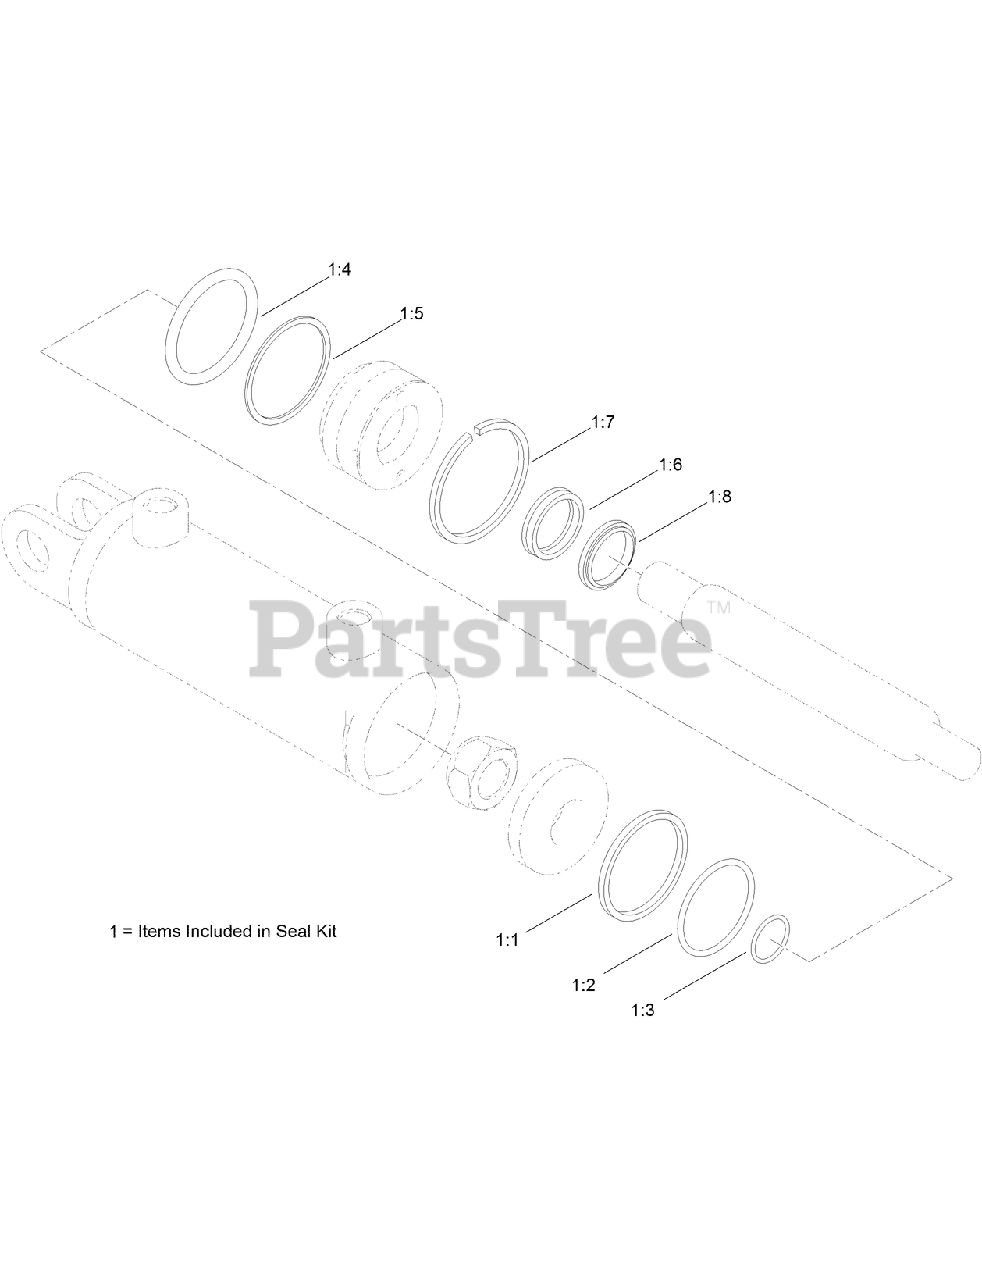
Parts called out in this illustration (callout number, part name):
1	SEAL KIT
1:1	SEAL-TEFLON, SQUARE
1:2	O-RING
1:3	O-RING
1:4	O-RING
1:5	Washer-Back Up
1:6	Seal-U Cup
1:7	RING-RETAINING
1:8	WIPER
1:9	RING-INSTALLATION
